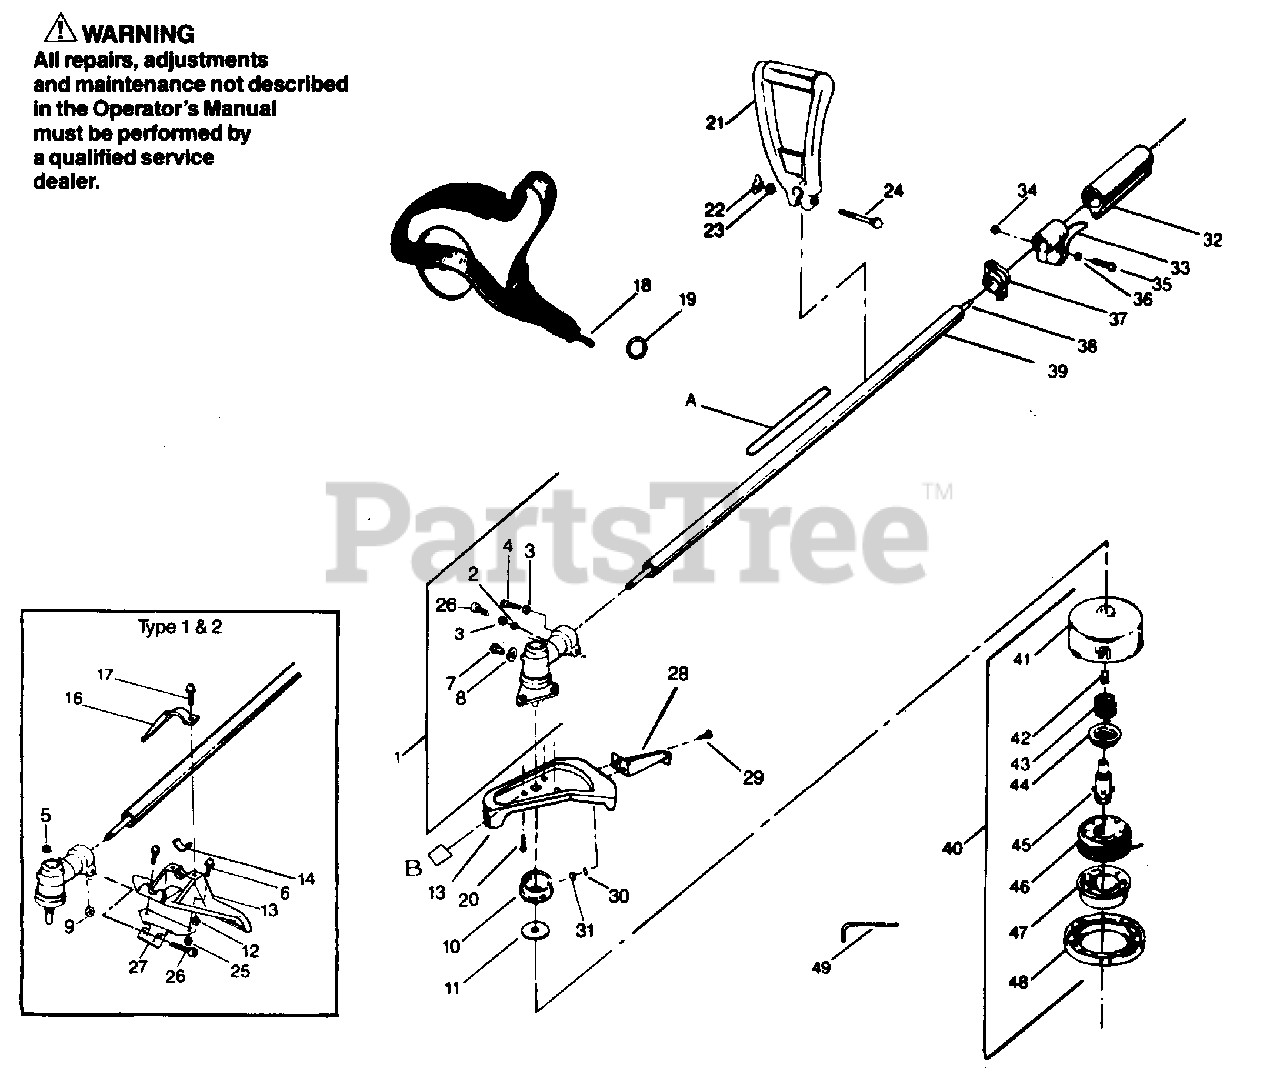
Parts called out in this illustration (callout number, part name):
1	Type 1 & 2
1	Type 3 & 4
2	Lockwasher - Type 2
2	Washer - Type 1, 3 & 4
3	Lockwasher - 5mm
4	Screw - 5 x 12.5mm - Soc. Hd. Gear Box - Index
5	Nut - 5mm - Type 2 only Gear Box - Pinch Clamp
6	Screw - Sems - 6 x 16mm - Type 2 only
7	Type 1 & 2
7	Type 3 & 4
8	Type 1 &2
8	Type 3 & 4
9	Washer - Spacer - Gear Box - Type 1 & 2
10	Adaptor - Upper
11	Adaptor - Lower
12	Nut - 6mm - Shield - Type 1 & 2
13	Type 3 & 4
14	Spacer - Shield - Type 1 & 2
16	Bracket - Top - Shield - Type 1 & 2
17	Screw - 6 x 20 mm - Shield - Type 1 & 2
18	Shoulder Strap
19	Key Ring Shoulder Strap
20	Screw - Type 3 & 4
21	Assist Handle
22	Wing Nut "D" Handle
23	Washer - Handle
24	Screw - Handle
25	Nut - Hex 6mm - Type 2 only
26	Type 1, 3 & 4 (5 x 25mm)
26	Type 2 (5 x 35mm)
27	Bracket - Lower - Splash Deflector - Type 2 only
28	Line Limiter - Type 3 & 4
29	Screw - Type 3 & 4
30	Washer - Type 3 & 4
31	Nut - Type 3 & 4
32	Grip - Drive Shaft Hsg.
33	Throttle Control Ass'y
34	Lock Nut - Hex - 5mm Throttle Control
36	Washer - Throttle Control
37	Clamp - Shoulder Strap
38	Type 2, 3 & 4
39	Type 2, 3 & 4
40	Cutting Head Ass'y (Incl. #41-48)
41	Hub w/Line Saver
42	Line Saver
43	Spring
44	Adaptor - Spring
45	Drive Gear
46	Spool w/Line
47	Release Button (Incl. Lock Ring)
49	Wrench - Hex - 4mm
B	Decal - Warning Shield
